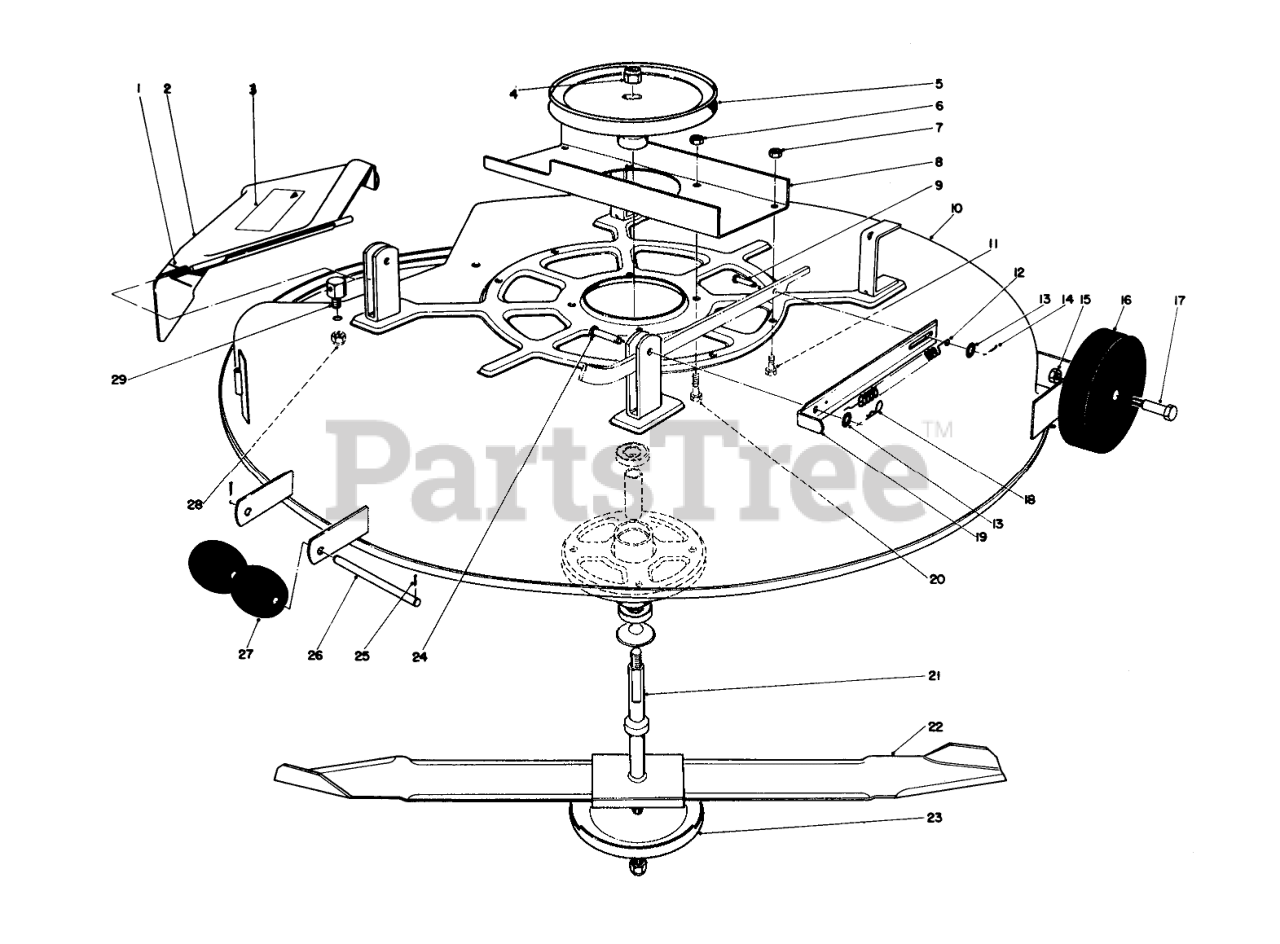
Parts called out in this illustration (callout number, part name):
1	SPRING
2	Deflector Assembly (Incl. Ref. #3)
3	Decal
5	PULLEY(BLADE DRIVE)
6	NUT-LOCK, CONE
7	NUT-HEX, SIDE DEFORM
8	Channel Reinforcement
9	PIN-CLEVIS
10	Cutter Deck
11	SCREW-HH
12	DECK TENSION SPRNG O
13	WASHER-FLAT
14	PIN-COTTER
15	Nut
16	DECK WHEEL
18	PIN-COTTER
19	Strap-Deck Spring
20	SCREW-HH
21	Spindle Assembly
22	Blade
23	Cup
24	PIN-CLEVIS
25	PIN-COTTER
26	ROLLER SHAFT
27	ROLLER
28	NUT-LOCK, SIDE
29	POST-PIVOT
